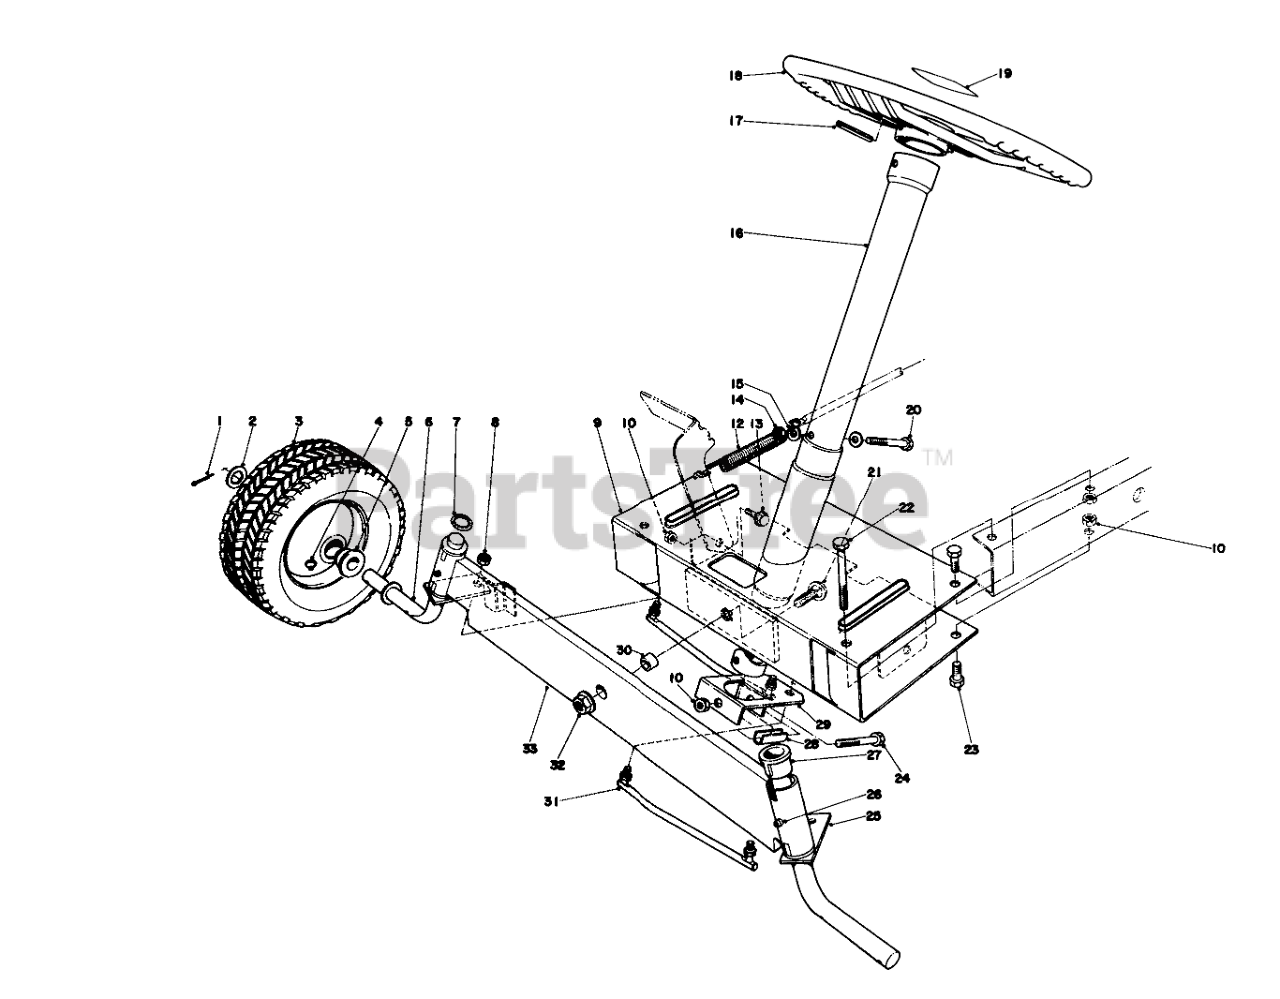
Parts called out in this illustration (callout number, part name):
1	PIN-COTTER
2	WASHER-FLAT
3	WHEEL & TIRE ASM
4	FITTING-GREASE
5	BUSHING
6	Spindle R.H.
7	RING-RETAINING
8	NUT-LOCK NI
9	Front Frame
10	NUT-LOCK, CONE
12	Brake Spring
13	SCREW-SHOULDER
14	NUT-LOCK, CONE
15	WASHER-FLAT
16	Steering Tube
17	PIN-ROLL
18	Steering Wheel
19	Decal
20	SCREW-HH
21	SCREW-CARR
22	SCREW-HH
23	SCREW-HH
24	SCREW-HH
25	Spingle L.H.
26	GREASE FITTING
27	BUSHING
28	Spacer-Steering Tube
29	Lever Steering
30	FRONT AXLE SPACER
31	TIE ROD ASM
32	NUT-HF
33	Front Axle
